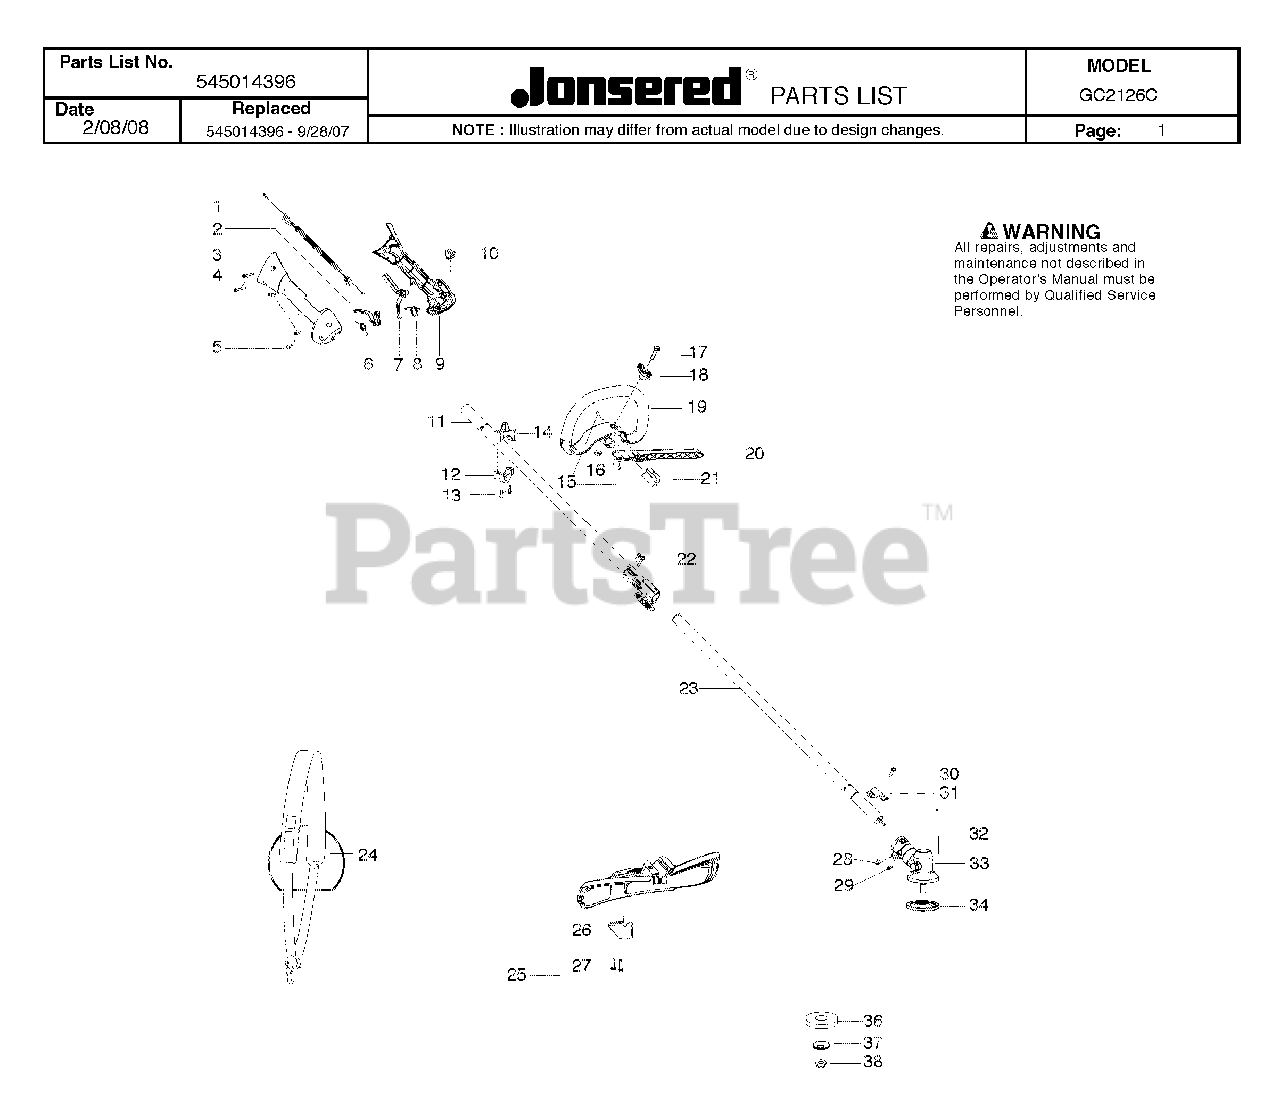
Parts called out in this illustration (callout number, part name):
5	SCREW M4 X 1.75 PT 16MM
6	SPRING TRIGGER
8	SPRING LOCKOUT
10	KIT SWITCH
12	CLAMP HARNESS LOWER
14	CLAMP HARNESS UPPER
24	STRAP
25	KIT SHIELD
26	LINE CUTTER
28	SCREW - CARB. ADAPTOR
30	SCREW 1/4-20 X 7/8 (TAP
31	BRACKET SHIELD STRAIGHT SHAFT
32	LOCKING PIN
33	ASSY GEARBOX
34	DRIVE DISC
36	SUPPORTING CUP
37	SUPPORT FLANGE
38	GEARHEAD NUT - BRUSHCUTTER
